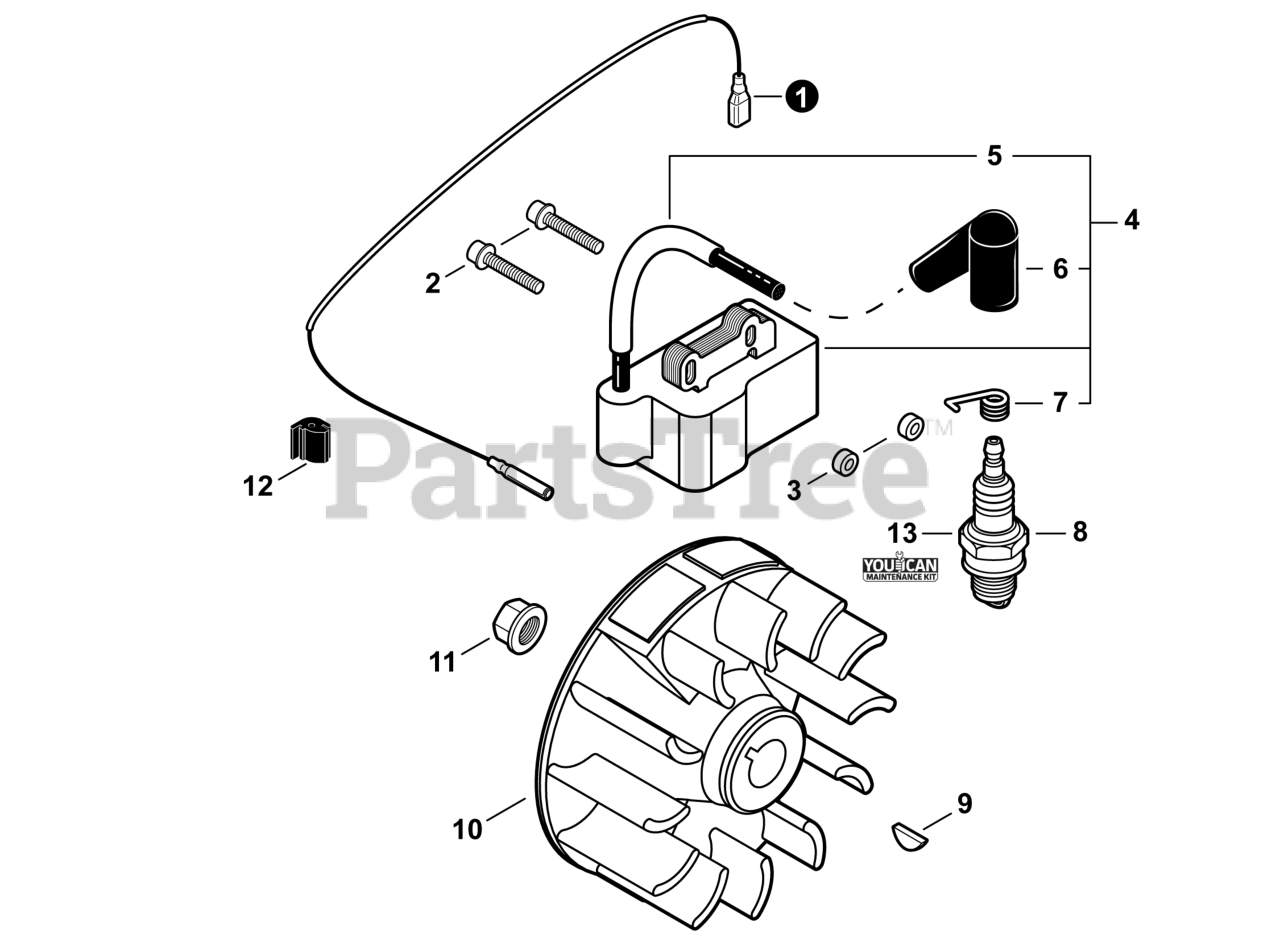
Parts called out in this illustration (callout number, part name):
1	LEAD - IGNITION
2	BOLT M4×26
3	INSULATOR 4.2×11×6
4	COIL ASSY, IGNITION
5	TUBE, INSULATOR
6	CAP, SPARK PLUG
7	TERMINAL, SPARK PLUG
8	SPARK PLUG - CMR5H
9	KEY, WOODRUFF 3×10
10	FLYWHEEL
12	GROMMET, LEAD
13	TUNE-UP KIT - YOUCANT
